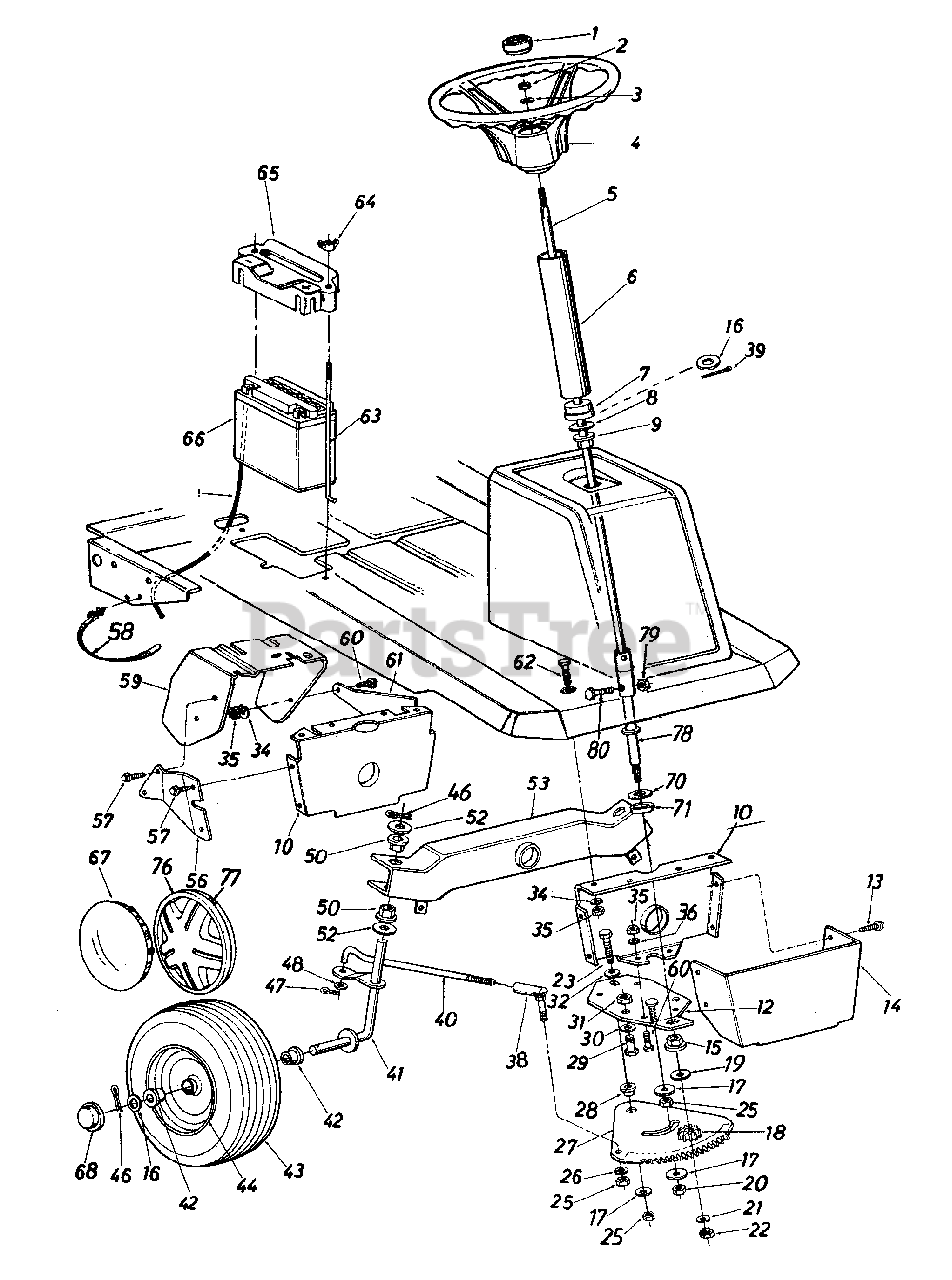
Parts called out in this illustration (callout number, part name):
1	Steering Wheel Cap
2	Hex L-Nut 5/16-24 Thd.
3	Bell-Wash. .345" I.D. x .88" O.D.
4	Steering Wheel Ass'y. (3 Spoke)
5	Steering Shaft Ass'y.
8	Fl-Wash. .635" I.D. x 1.24" O.D.
9	Hex Flange Bearing
13	Hex Wash. Hd. AB-Tap Scr. 1/4 x .62" L
16	Fl-Wash. .640" I.D. x 1.5" O.D.
17	Fl-Washer 3/8" I.D. x 1.37" O.D.
18	Steering Pinion Gear
19	Fl-Wash. .510" I.D. x 1" O.D.
20	Hex L-Nut 3/8-24
21	Fl-Wash. .34" I.D. x .68" O.D.
22	Hex Nut 5/16-24 Thd.
23	Hex Bolt 3/8-24 x 1.5" Lg. (Grade 5)
25	Hex Nut 3/8-24 Thd.
26	L-Wash. 3/8" I.D.
27	Steering Gear Segment
28	Shoulder Spacer .622" Dia. x .218
29	Hex Bolt (Nylon) 1/2-13 x .75"
30	Fl-Wash. .530" I.D. x .930"
31	Hex Nut 1/2-13 Thd.
32	Bell-Wash. .385" I.D. x .88"
36	Spr. Wash. .32" I.D. x .62" O.D.
38	Ball Joint Ass'y. 3/8-24 Thd.
39	Cotter Pin 1/8" Dia. x 1.00" Lg.
40	Steering Tie Rod
41	Front Axle Ass'y.-R.H.
42	Flange Bearing
46	Cotter Pin 1/8" Dia. x 1.25"
47	Cotter Pin 1/8" Dia. x 1.00"
48	Fl-Wash. .385" I.D. x .87"
50	Hex Flange Bearing
52	Fl-Wash. .635" I.D. x 1.12"
58	Cable Tie
59	Clutch-Brake Pedal Ass'y.
60	Hex Bolt 5/16-18 x .75" Lg.
63	Battery Hold Down Rod
64	Wing Nut Solid 1/4-20 Thd.
65	Battery Hold Down Cover
66	12V Battery
67	Chrome Hub Cap
68	Plastic Hub Cap
70	Fl-Wash. .635" I.D. x 1.24" O.D.
71	Spacer (Plastic)
76	Hub Cap-Beige
77	Spring Clip
78	Steering End Adapter
79	Hex Nylon L-Nut 1/4-20 Thd.
80	Hex Bolt 1/4-20 x 1.31" Lg.
